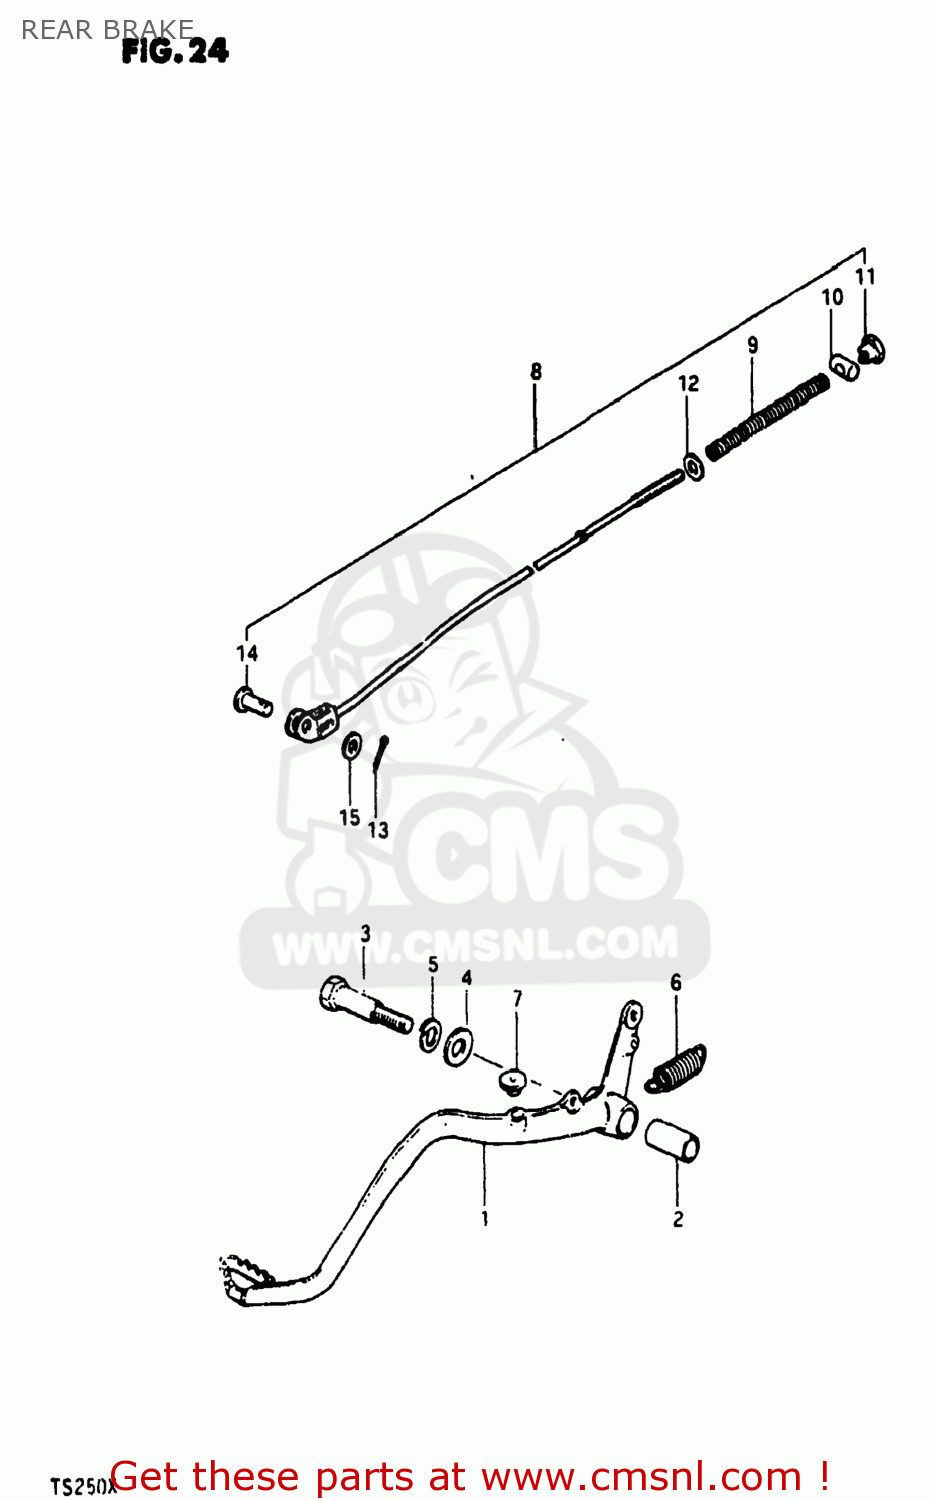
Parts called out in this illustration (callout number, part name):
1	PEDAL,BRAKE
2	SPACER(10.5X16X30)
3	BOLT
4	WASHER
5	LOCK WASHER
6	SPRING
7	STOPPER,BRAKE PEDAL
8	ROD ASSEMBLY,REAR BRAKE
9	SPRING
10	PIN(11X18)
11	NUT
12	WASHER
13	PIN 20X20
14	PIN(L:13.5)
15	WASHER
